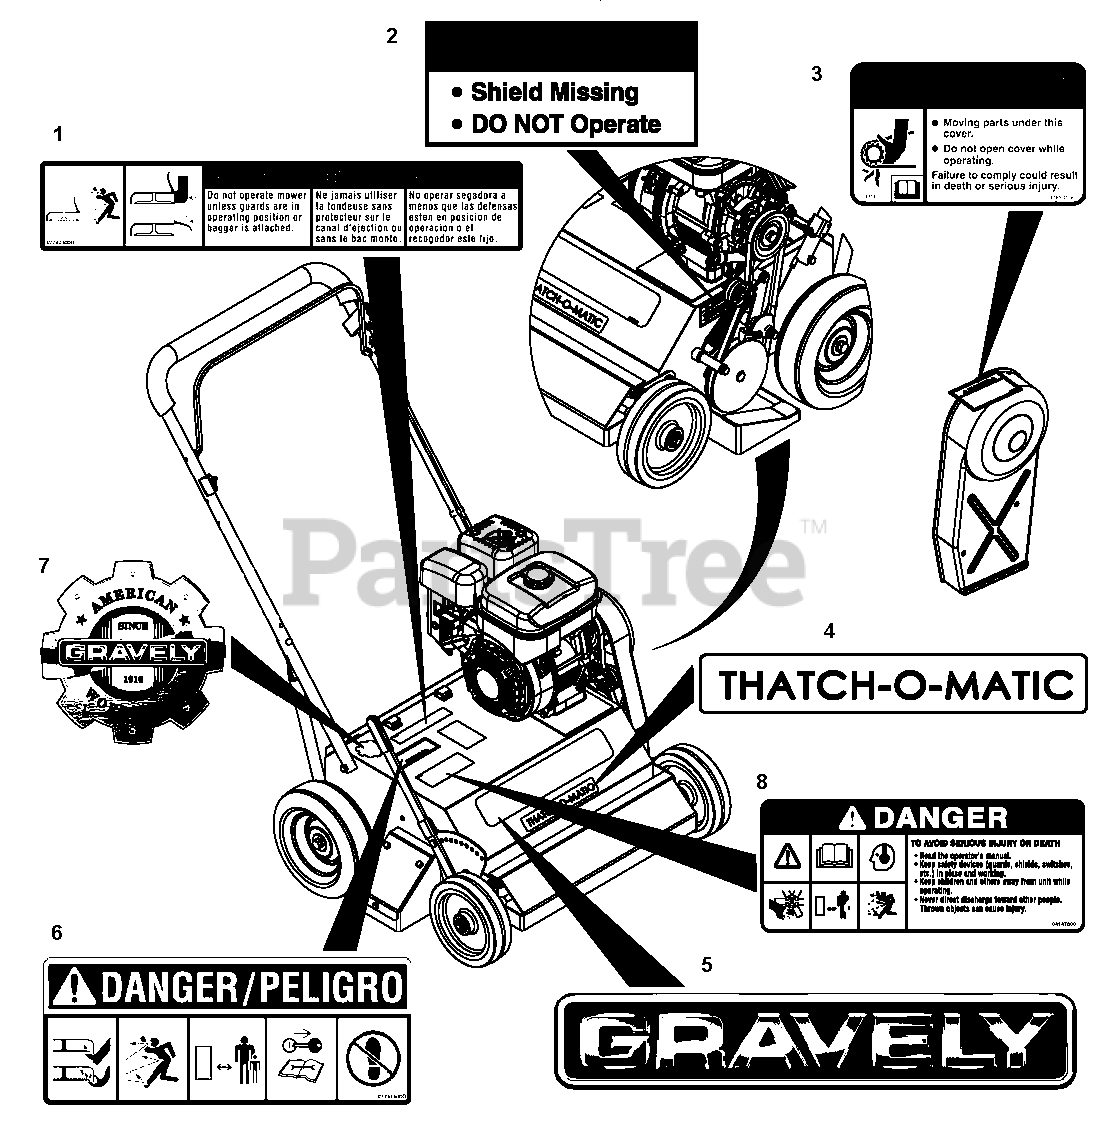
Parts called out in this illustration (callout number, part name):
1	Decal, Warning
2	Decal, Warning, Shield
3	Decal, Warning, Moving Parts
4	Decal, THATCH-O-MATIC
5	Decal, 15" Gravely Logo
6	Decal, Mower Pan Danger
7	Decal, Gravely Heritage, Small
8	Decal, Danger Read Manual
